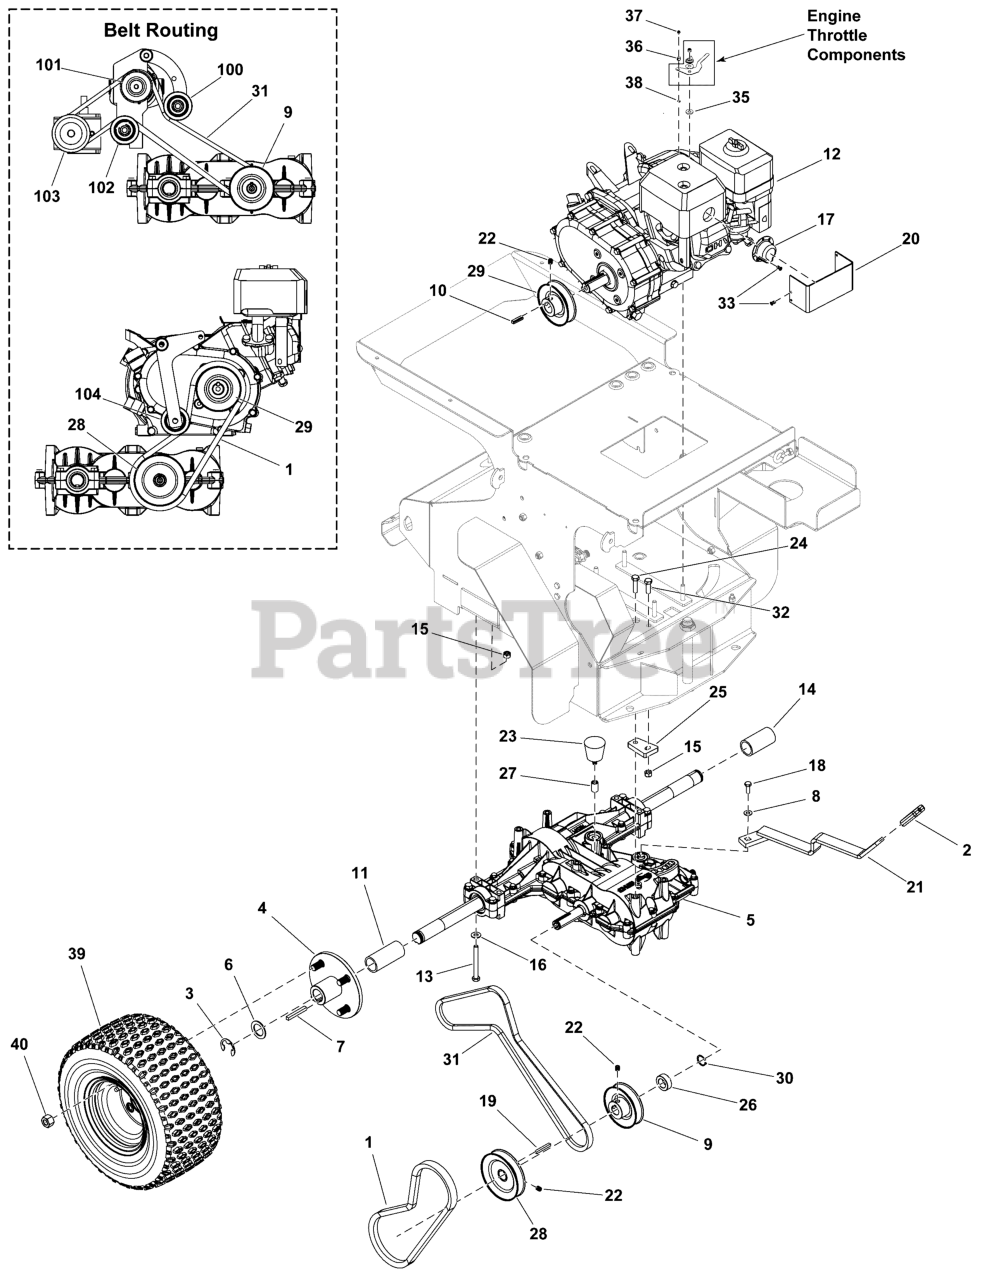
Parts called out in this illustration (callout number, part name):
1	BELT, V, BX26 29.00 OC
2	GRIP, .188" X 1.00" ID X .150" THK CLSD CELL FOAM
3	E-RING, 1.000" SHAFT YZ
4	HUB, 1.00" BORE 4-BOLT X 4.00" BC
5	TRANSMISSION, PEERLESS 855-007D
6	WSHR-STL, FLT 1.000"X1.500"X.075" MAB ZP
7	KEY, .250" SQ. X 2" SS188
8	WSHR-SS, BLV .281"X.875"x.066
9	PULLEY, 3.50" O.D. x 0.750" I.D. V, A/B
10	KEY, .188"-.250" STEPPED X 1.00" LONG SS 304
10	KEY, Drive Pulley
11	SPCR-PVC 1.049" X 1.315" X 3.000
12	ENGINE, PATHFINDER/XC
13	SCR-CAP, HEX .3125"-18 X 3.000" SS188
14	SPCR-PVC 1.049" X 1.315" X 2.850"
15	NUT-HEX-NYLK, 0.3125"-18 SS188
16	WSHR-STL, FLT .343" X .750" X .050" SPC SS188
17	DEFLECTOR, EXHAUST HONDA GX160/GX200
18	SCR-CAP, HEX .250"-28 X 0.750" SS188
19	KEY, .188" SQ. X 1.50" SS303
20	PLATE, VALVE MOUNTING
21	WELD, GEAR SHIFT LEVER
22	SCR-SH, SET .3125"-18 X .375" KCPT SS188
23	BUMPER, 1.188OD X 1.50LG W/.3125-18 STUD
24	SCR-CAP, HEX .3125"-18 X 1.250" SS188
25	PLATE, SPACER, TRANSMISSION
26	SPCR-UHMW .765" X 1.250" X .450"
27	SPACER, 0.50" OD X 5/16"-18 THRD X .80" LNG
28	PULLEY, 4.00" O.D. x 0.750" I.D. V, A/B
29	PULLEY, 3.50" O.D. x 0.875" I.D. V, A/B
29	PULLEY, Crankshaft
30	RING, RETAINING EXTERNAL 3/4" ZP
31	BELT, A-SEC, A43 (C0152)
32	SCR-CAP, HEX .3125"-18 X 1.000" SS188
33	RIVET, BLIND .125" X 250" SS188
35	WASHER, Nylon, Flat, .385" X .880" X .125"
36	RETAINER, WIRE HEX 10MM
37	SCREW, HEX WASHER HEAD M4 X 0.7 - 6H
38	RING, RETAINING
39	ASM, WHEEL&TIRE 18" X 9.50" W/ANTI-FREEZE
39-1	TIRE, 18" TURF
39-2	Wheel Only
40	NUT-LUG, .500"-20 ZP
100	PUMP IDLER PULLEY
101	PUMP PULLEY
102	STATIONARY IDLER PULLEY
103	GEARBOX PULLEY
104	TRANSAXLE IDLER PULLEY
